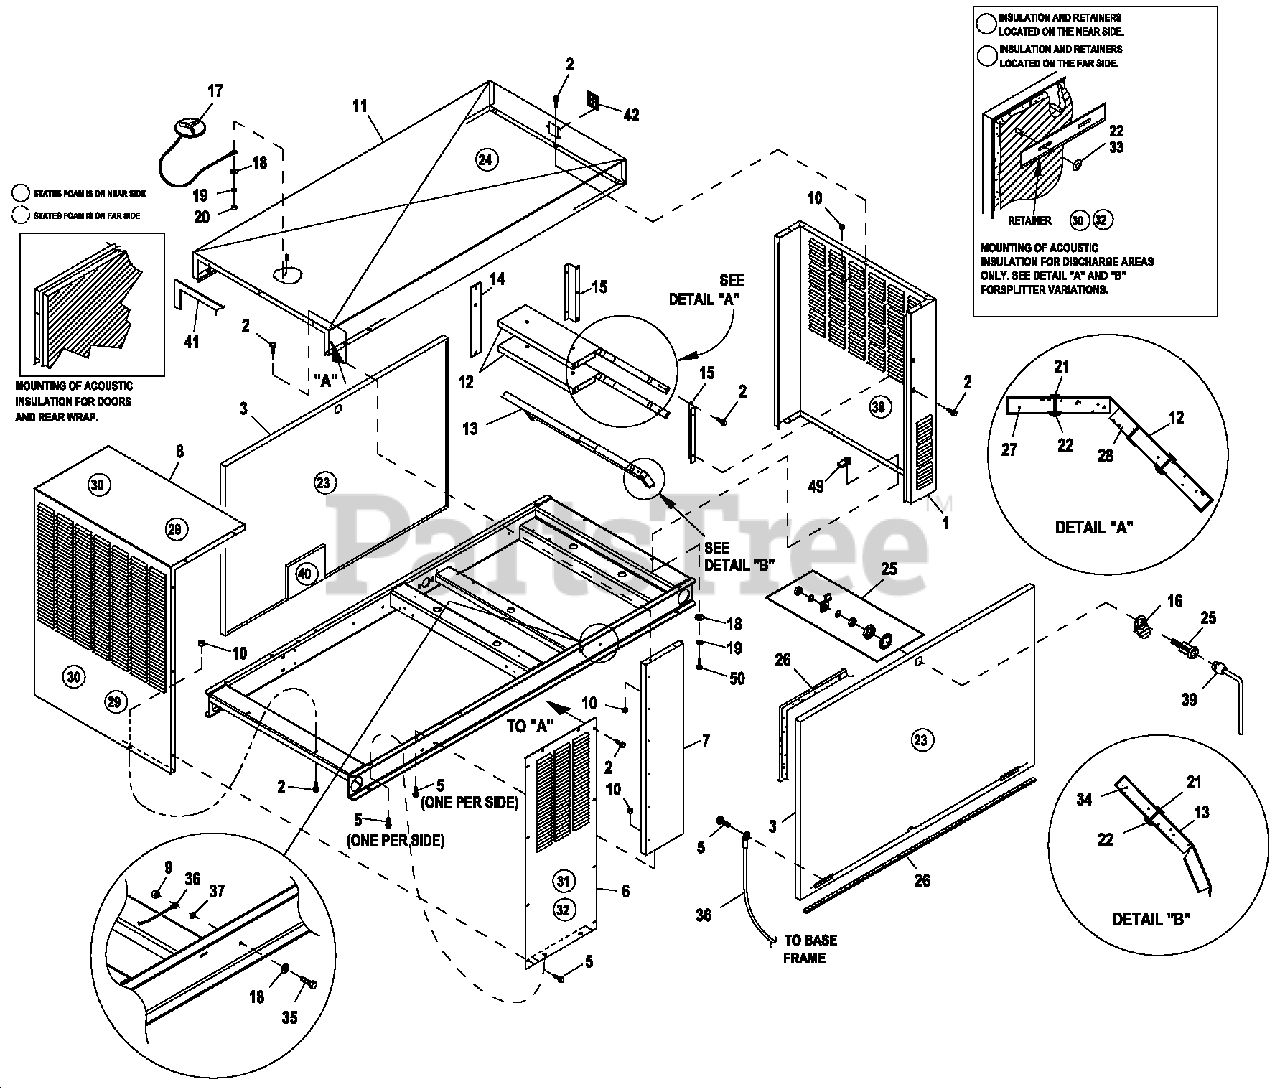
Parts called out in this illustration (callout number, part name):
1	ROTOR-2390-45KD1 CPL
2	ROTOR-2390-35KD1 CPL
3	ROTOR-2390-45KD1 CPL (G2)
4	ROTOR-2390-35KD1 CPL (G2)
5	ROTOR 25KW 3PH DIRECT 390 1800
6	ROTOR 25KW 1PH DIRECT 390 1800
7	FRONT CORNERS C2
8	DISCHARGE CENTER DUCT C2
9	NUT HEX M 6X1.0 G8 YELCHR
10	STATOR-390 45K 2P 1PH DIRECT
11	STATOR-2390-35AD1 CPL
12	STATOR-2390-35KD1 CPL
13	STATOR-2390-35GD1 CPL
14	STATOR-2309-45KW 2P 3PH 208V
15	STATOR-2309-45-KD1 CPL
16	TAB PULL
17	ASSEMBLY COVER ACCESS
18	WASHER FLAT 1/4-M6 ZINC
19	WASHER LOCK M6-1/4
20	NUT HEX 1/4-20 STEEL
21	INSULATION RETAINMENT HANGER
22	WASHER SELF LOCKING DOME #4-40
23	INSULATION D OOR C2
24	INSULATION ROOF TOP
25	VISE-ACTION LATCH SLOTTE D CIR
26	GASKET EXTRUDED TRIM (328" LG)
27	INSULATION SPLITTER
28	INSULATION SPLITTER
29	INSULATION D UCT
30	RETAINER INSULATION (820)
31	INSULATION D UCT SI D ES
32	RETAINER INSULATION (450)
33	WASHER SELF LOCKING DOME #8-32
34	INSULATION LOWER SPLITTER
35	SCREW HHC M6-1.0X20 G8.8
36	ASSY WIRE 14 AWG 34.8" GRN/YEL
37	WASHER SHAKEPROOF INT 1/4
38	INSULATION REAR WRAP
39	KEY VISE-ACTION LATCH SLOT CIR
40	FOAM 300 X 300 THERMAL ACO (APPLIES TO 4.2L UNITS ONLY)
41	STRIP SEALANT 1/8X 1 (44.52"LG)
42	RF COVER PLATE-PLASTIC-BISQUE
49	NUT UM6-1.0 GEOMET
50	SCREW HHFC M6-1.0X 2 0 G8.8
